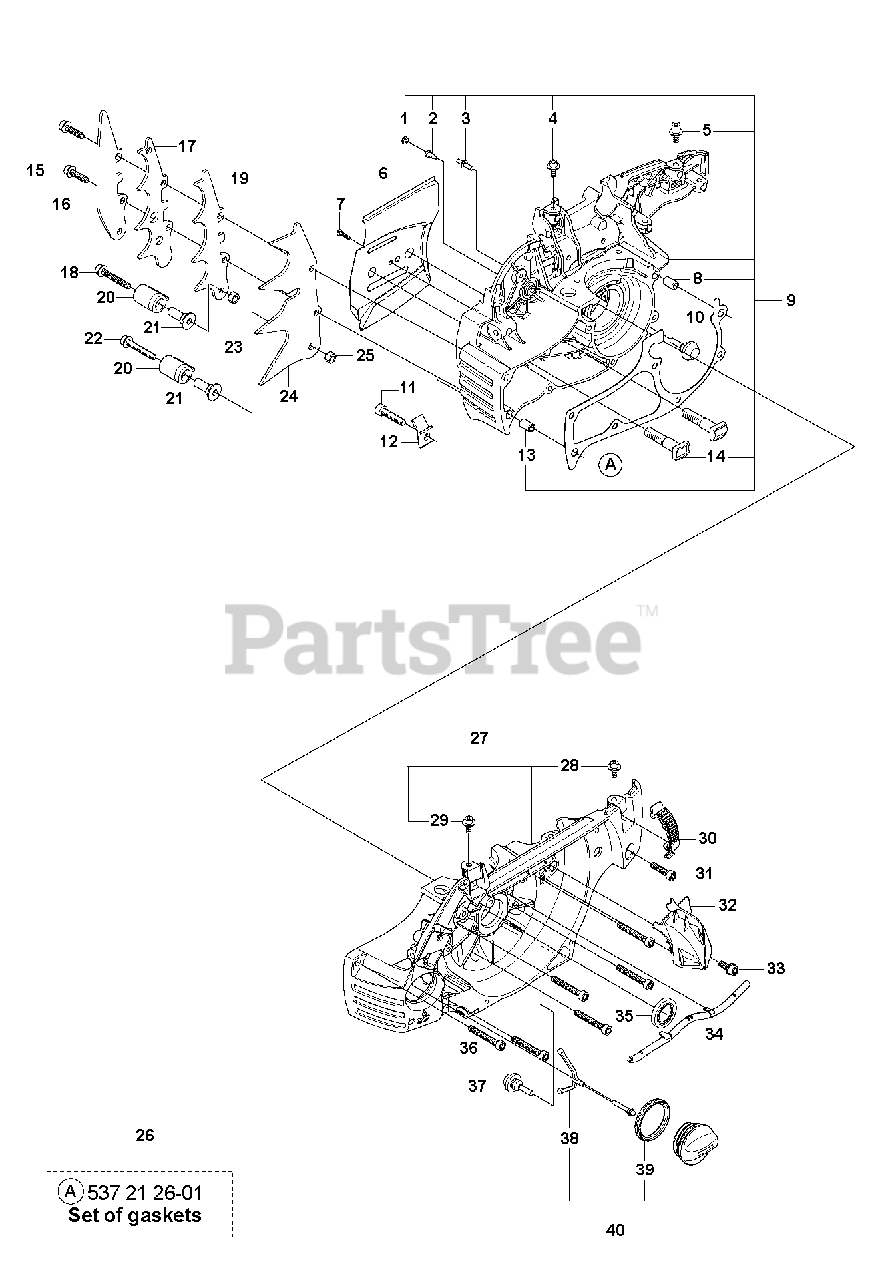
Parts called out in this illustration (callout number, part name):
1	PLUG
2	VALVE-CHECK (DUCKBILL)
3	PIN
4	SCREW IHSCM
5	SCREW IHSCM
8	SLEEVE
9	RP CRANKCASE ASSEMBLY
12	CHAIN CATCHER
13	SLEEVE
14	BOLT
17	FELLING DOG
18	SCREW IHSCFM
19	FELLING DOG
21	CHAIN CATCHER
22	SCREW
24	FELLING DOG
26	GASKET SET
27	RP CRANKCASE ASSEMBLY
28	SCREW IHSCM
29	SCREW IHSCM
30	BUCKLE ORANGE
35	RADIAL SEAL
38	TANK LOCK
39	SEALING
40	TANK CAP
